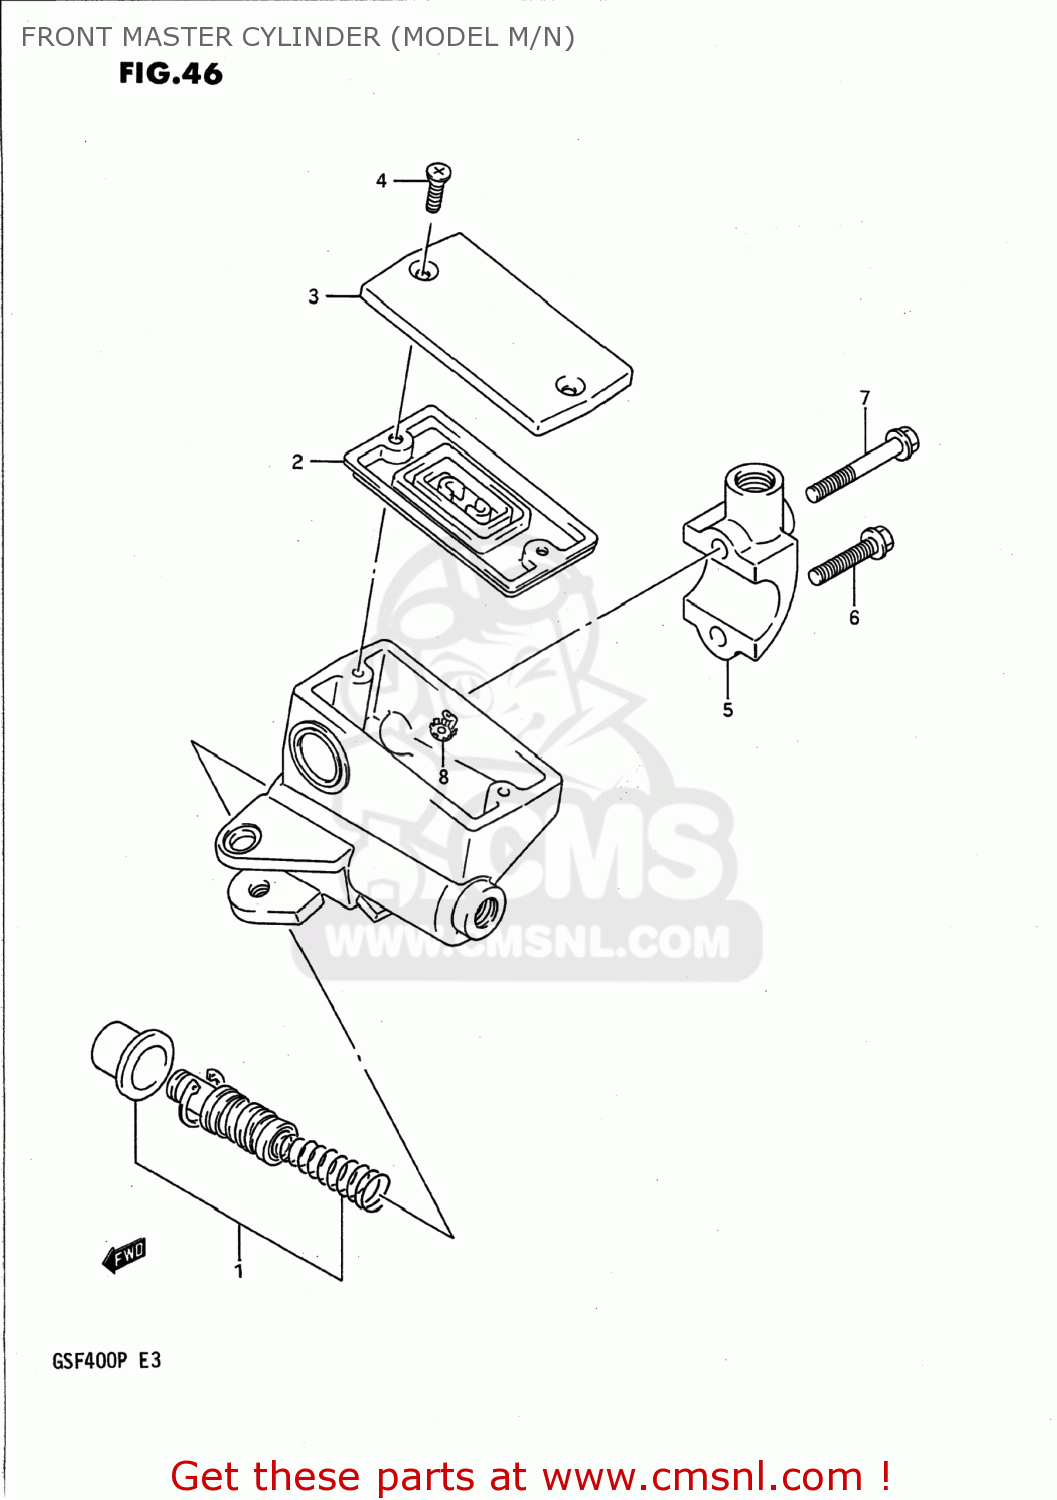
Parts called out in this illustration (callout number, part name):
1	CUP SET,MASTER CYLINDER
2	3
3	CAP
4	SCREW
5	HOLDER
6	BOLT(6X25)
7	BOLT(6X38)
8	PROTECTOR
